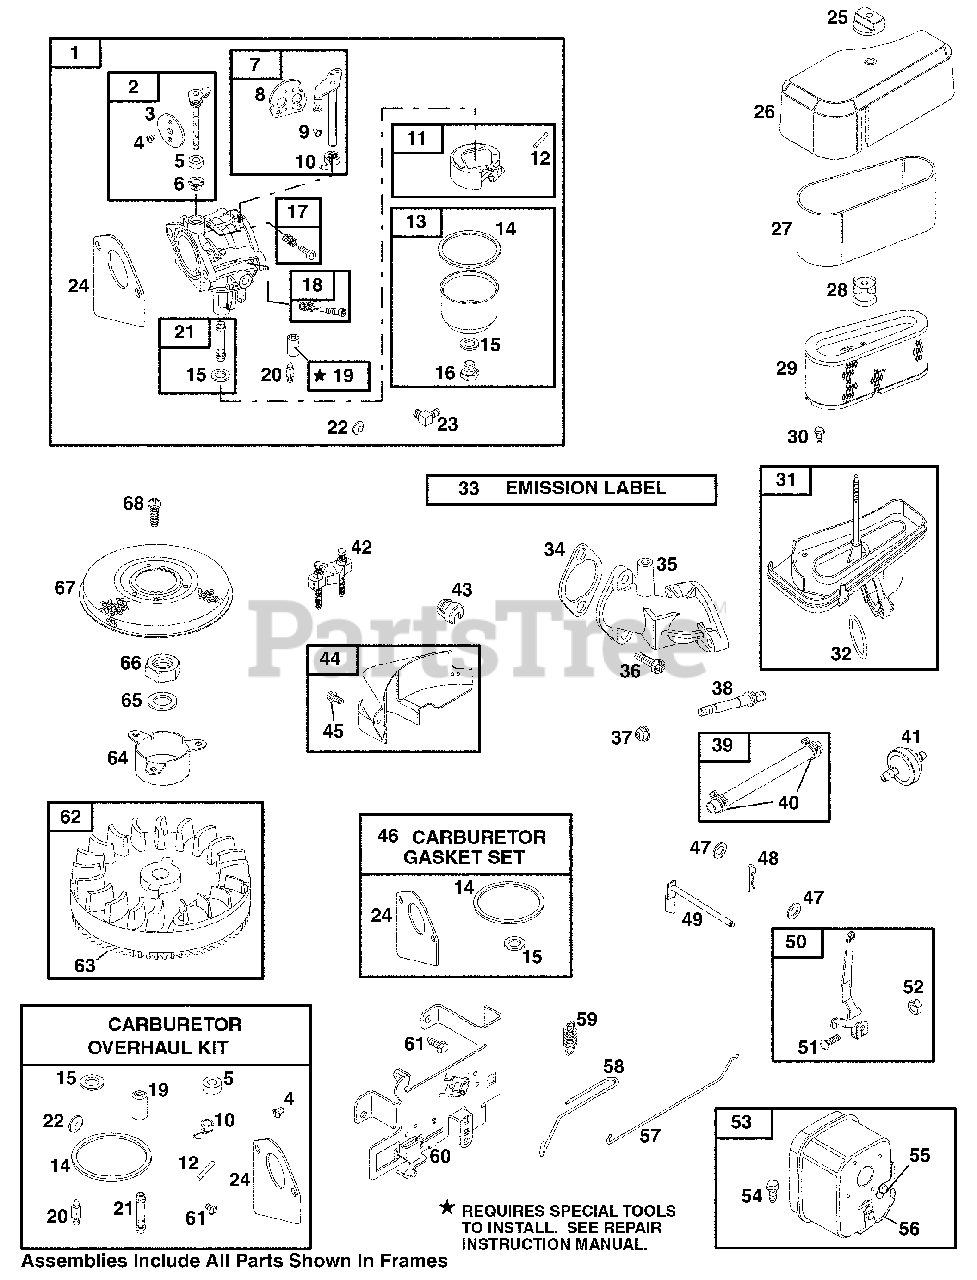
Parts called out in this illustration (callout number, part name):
1	Carburetor
2	Throttle Shaft Kit
3	Throttle Valve
4	Screw
5	Seal-Throttle Shaft
6	Bushing-Throttle Shaft
7	Choke Shaft Kit
8	Valve-Choke
9	Screw
10	Spring & Seal Assembly
11	Float-Carburetor
12	Pin-Float Hinge
13	Bowl-Float
14	Gasket-Float Bowl
15	Sealing Washer
16	Screw
17	Kit-Idle Speed
18	Kit-Idle Mixture
19	Inlet Seat
20	Float Needle Valve
21	Nozzle-Carburetor
22	Plug-Welch
23	Connector-Hose
24	Intake Gasket
25	Knob-Air Cleaner
26	Cover-Air Cleaner
27	Filter-Pre Cleaner
28	Seal-Air Cleaner Stud
29	Filter-A/C Cartridge
30	Screw
31	Base-Air Cleaner
32	O-Ring Seal
33	Label-Emissions
34	Intake Gasket
35	Intake Manifold
36	Screw
37	Nut
38	Stud
39	Line-Fuel
40	Clamp-Hose
41	Filter-Fuel
42	Flywheel Puller
44	Cover-Starter Drive
45	Screw
46	Carburetor Gasket Set
47	Washer
48	Pin-Cotter
49	Crank-Governor
50	Governor Control Lever
51	Bolt
52	Nut
53	Muffler-Exhaust
54	Screw
55	Screw
56	Shield-Heat
57	Mechanical Governor Link
58	Choke Link
59	Governor Spring
60	Bracket-Control
61	Screw
63	Gear-Ring
64	Cup-Flywheel
65	Washer
66	Nut
67	Rotating Screen
68	Screw
